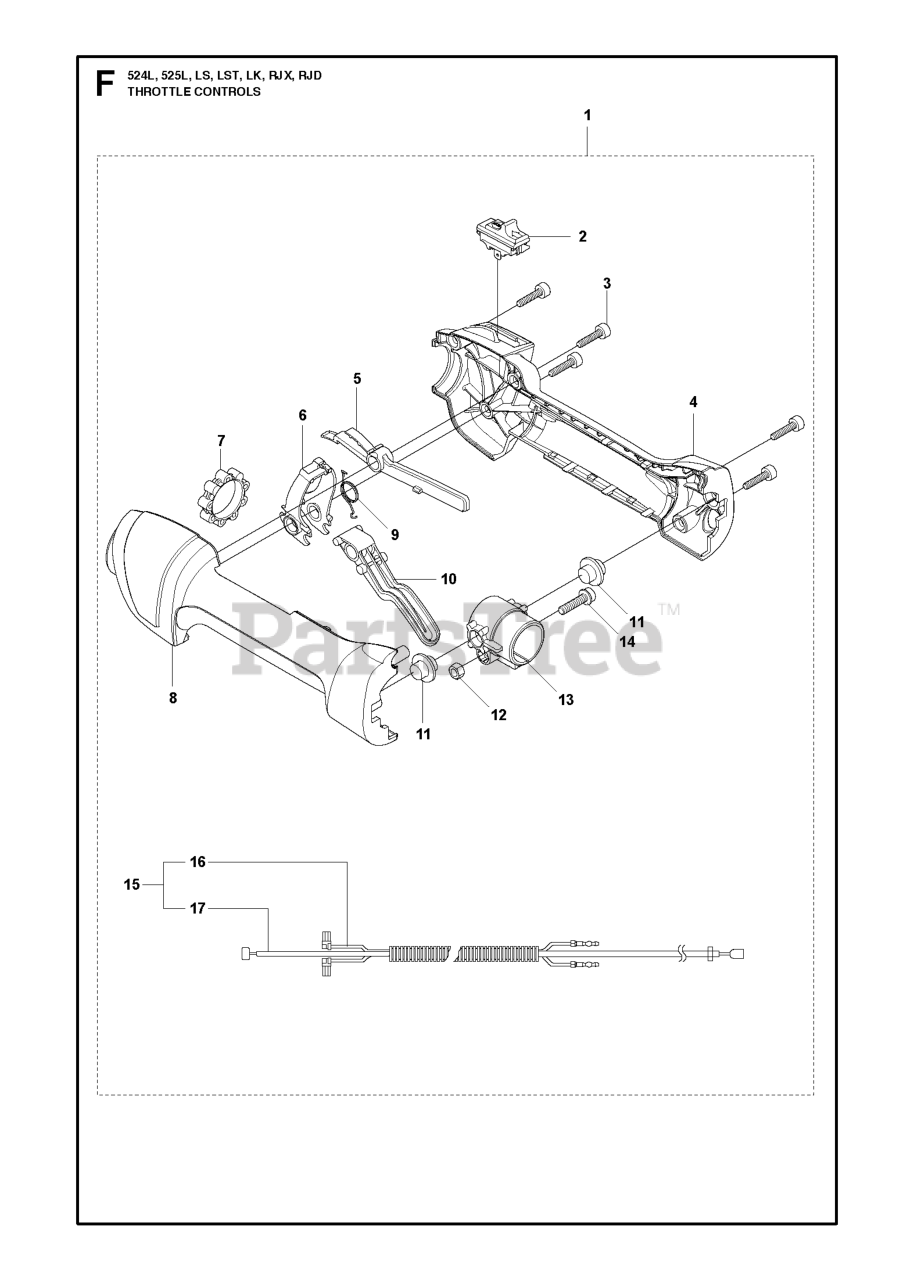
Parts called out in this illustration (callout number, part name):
1	THROTTLE CONTROL
1	THROTTLE CONTROL ASSY
2	STOP BUTTON
3	SCREW
4	HANDLE
5	THROTTLE LOCK
6	LEVER
7	VIBRATION DAMPER
8	HANDLE
9	RETURN SPRING
10	THROTTLE TRIGGER
11	VIBRATION ABSORBER
12	NUT
13	HOLDER
14	BOLT TORX
15	WIRING ASSY
16	SHORT CIRCUIT CABLE
17	THROTTLE CABLE
